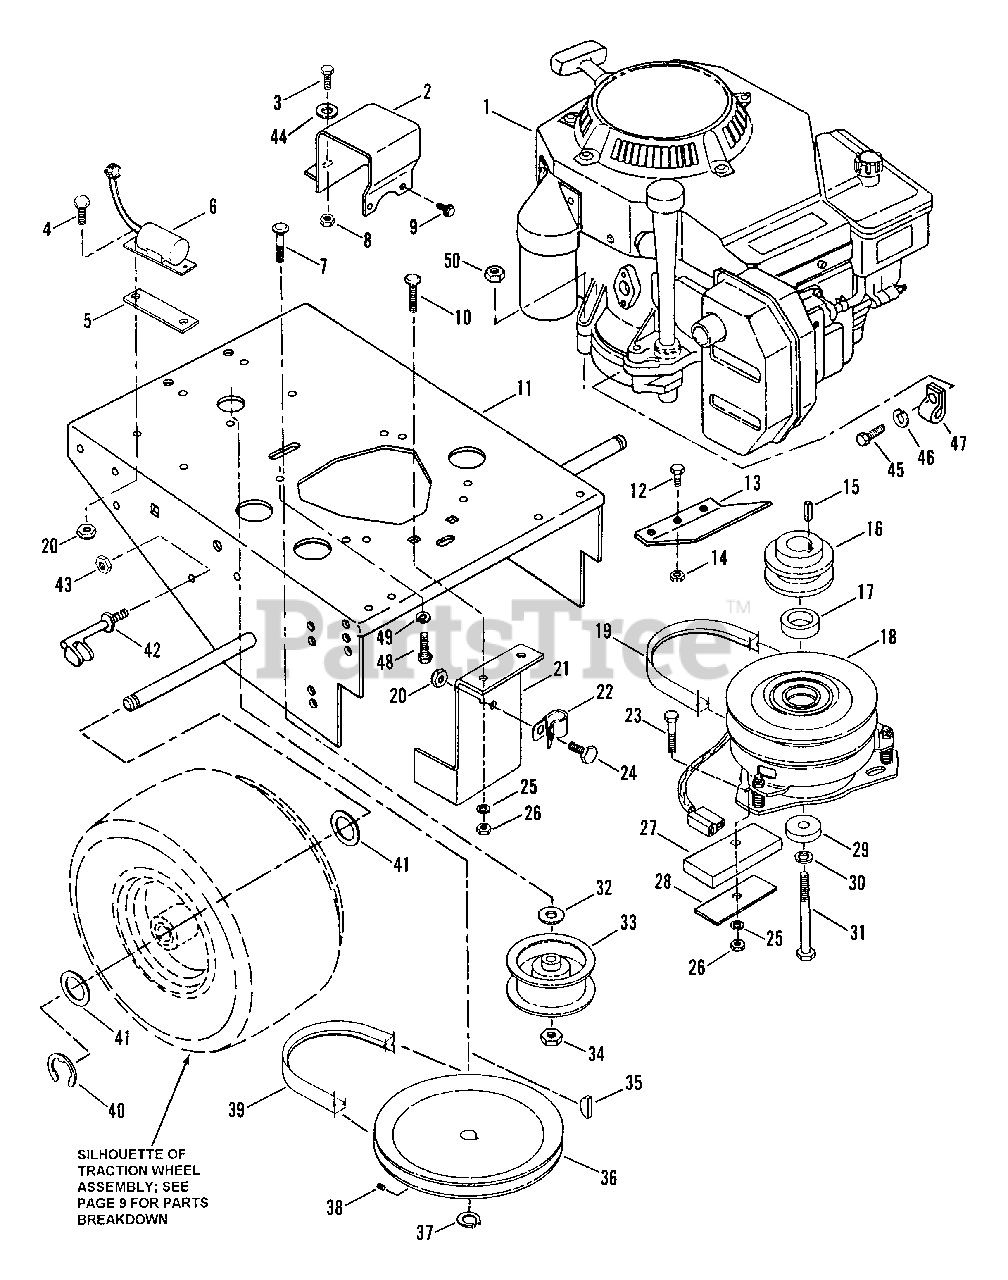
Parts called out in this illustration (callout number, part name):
1	ENGINE,12.5 HP Kohler
2	SHIELD, Heat (Briggs & Stratton Engine)
3	SCREW, 010-24 x 1/2" Hex Head, Machine
4	BOLT, 5/16-18 X 1 GD5 YZ
5	MOUNT, Capacitor (Kawasaki Engines Only)
6	CAPACITOR (Kawasaki Engines Only )
7	BOLT, 3/8-16 x 1 3/4" Short Neck Carriage, Grade 5
8	NUT, #10-24 Hex Nyloc
9	SCREW, #8-18 x 1/2" Hex Head, Self-Tapping
10	BOLT, 5/16-18 x 1" Short Neck Carriage, Grade 5
11	ASSEMBLY, Rear Deck
12	SCREW, 5/16-18 x 3/4" Hex Head Cap
13	SHIELD, Heat (Kawasaki & Kohler Engines Only)
14	NUT, 5/16-18 HEX NYLON LOCK
15	KEY, 1/4" x 1/4" x 11/16" Square (Kawasaki & Kohler Engines)
16	PULLEY, Engine/Transmission
17	BUSHING
18	CLUTCH, Electric
19	BELT, Engine/Deck
20	NUT, 5/16-18 HEX NYLON LOCK
21	BRACKET, Electric Clutch
22	CLIP, Wire Harness
23	BOLT, 5/16-18 X 1-1/4 GD5 YZ
24	BOLT, 5/16-18 X 3/4 GD5
25	WASHER, 5/16 Split Lock
26	NUT, 5/16-18 Hex, Grade 5
27	BUMPER, Rubber
28	PLATE, Rubber Bumper
29	SPACER
30	WASHER, 7/16 Split Lock
31	BOLT, M10-1.5 x 75.0mm Hex Head Cap, Grade 8.8
32	WASHER, Flat, 1.06 O.D. x .531 I.D. x .12"
33	PULLEY, Idler
34	NUT, 3/8-16 HEX NYLON LOCK
35	KEY, No. 9 Woodruff
36	PULLEY, Transmission
37	RING, Retaining
38	SET SCREW, 1/4-20 X 3/8" CONE
39	BELT, Engine/Transmission
40	E-RING, 1"
41	BUSHING, Axle
42	SCRAPER, Wheel
43	NUT, 3/8-24 Hex Center Lock
44	WASHER, #10 Flat
45	SCREW, M6-1.0 x 10mm Hex Head Cap
46	WASHER, 1/4 Split Lock
48	BOLT, M8-1.25 X 25MM GD8.8
49	WASHER, 5/16 Split Lock
50	NUT, 5/16-18 Hex
